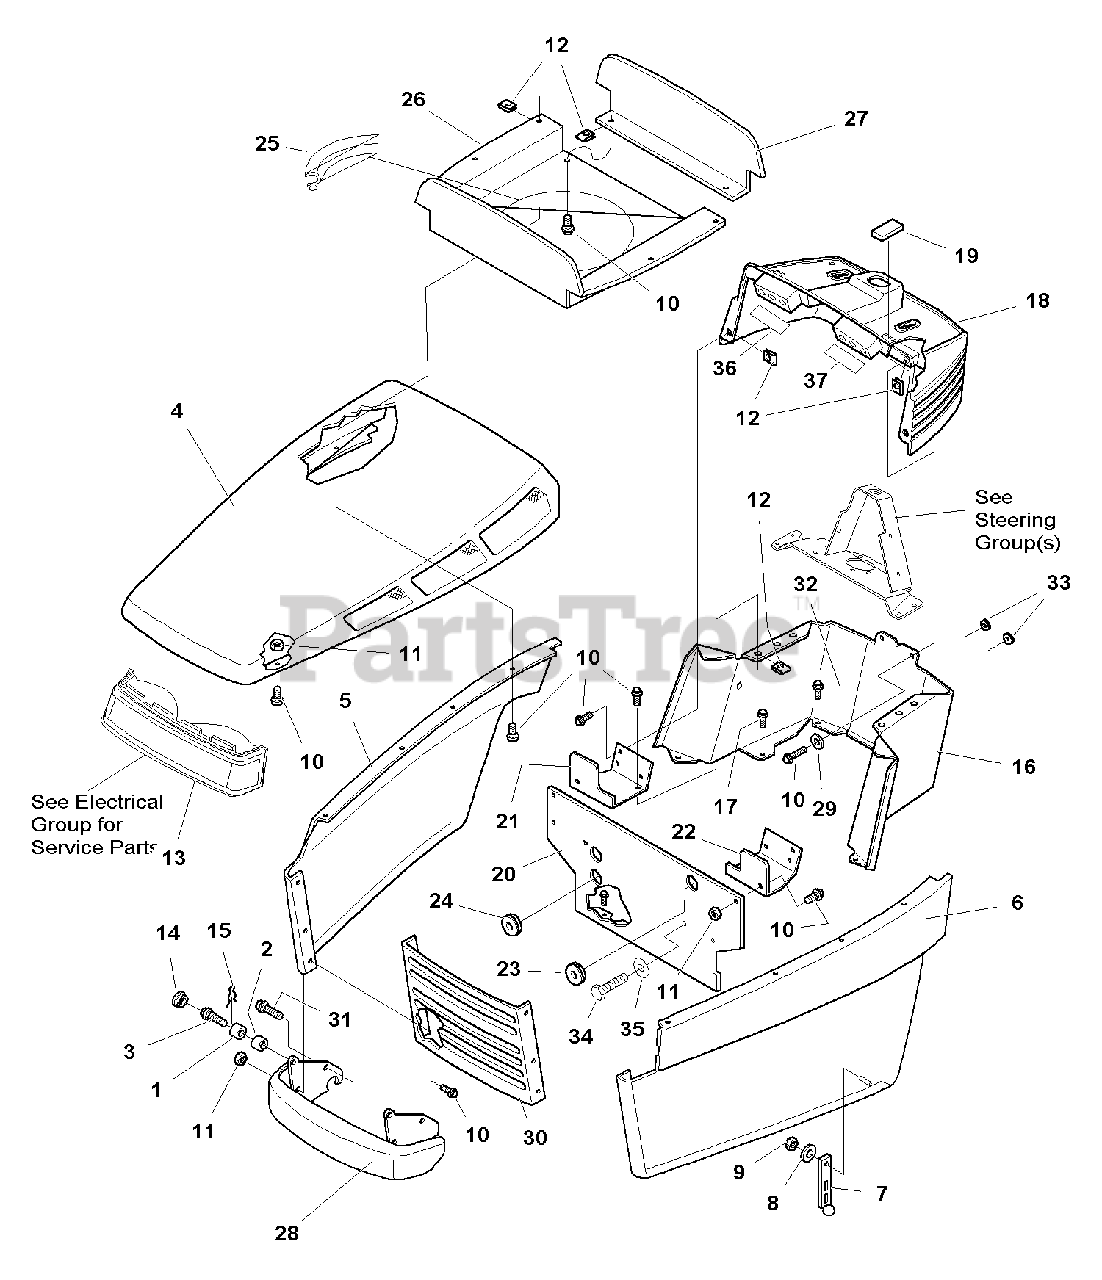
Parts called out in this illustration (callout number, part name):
2	PIVOT, Hood
3	CAPSCREW, Hex Head, Taptite, 5/16-18 X 1
4	HOOD, Orange
5	SIDE PANEL ASSEMBLY, RH, Orange
5	SIDE PANEL ASSEMBLY, RH, Red
6	SIDE PANEL ASSEMBLY, LH, Orange
6	SIDE PANEL ASSEMBLY, LH, Red
7	STRAP, Hood
8	WASHER, 3/16
9	NUT, Hex Nylon Lock, #10-24
10	CAPSCREW, Hex Head, Whiz Lock, 1/4-20 x 5/8
11	NUT, Hex Nylon Lock, 1/4-20
12	PAL NUT, 1/4-20
13	HEADLIGHT ASSEMBLY (See Electrical Group for Service Parts)
14	SPACER, Hood
15	CLIP, Hairpin
16	DASH ASSEMBLY, Lower
17	CAPSCREW, Hex Head, Taptite, 1/4-20 x 1/2
18	DASHBOARD ASSEMBLY (Air Cooled Models)
20	BULKHEAD
21	SUPPORT, Bulkhead, RH
22	SUPPORT, Bulkhead, LH
23	GROMMET, Bulkhead
24	GROMMET, Wire Harness
25	SEAL, Bulkhead
28	BUMPER ASSEMBLY
29	WASHER, 1/4
30	GRILLE
31	CAPSCREW, Hex Head, Taptite, 5/16-18 x 5/8
32	CAPSCREW, Hex Head, Taptite, 1/4-20 x 3/8
34	CAPSCREW, Hex Head, 5/16-18 x 5/8
35	WASHER, 5/16
36	DECAL, R. H. Indicator
37	DECAL, L. H. Indicator
